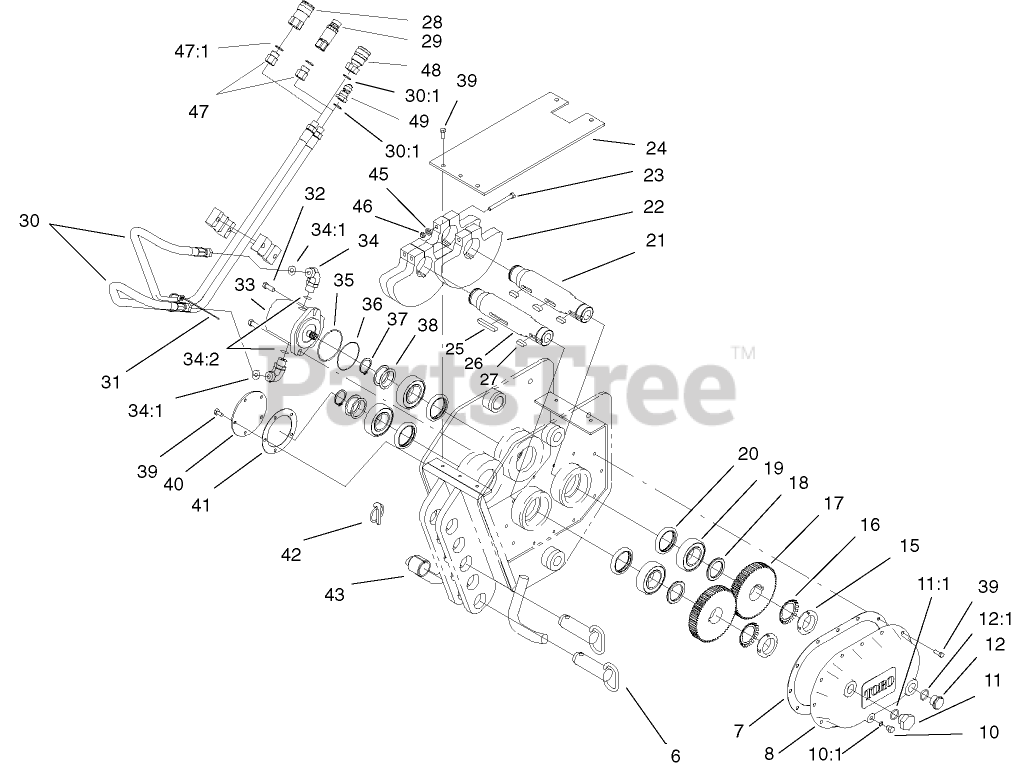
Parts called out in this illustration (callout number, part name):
6	BLADE PIN ASM
7	GASKET
10:1	O-RING
11	PLUG-HH
11:1	O-RING
12	GLASS-SIGHT
12:1	O-RING
16	RETAINER-NUT
18	SPACER
19	BEARING-ROLLER, SPHERICAL
20	SEAL-OIL
21	SHAFT-SPLINED
22	Weight-Counter
23	SCREW-HH
24	PLATE-TOP
25	KEY-LONG
26	SHAFT
27	KEY-SHORT
28	COUPLER-FACE, FLUSH
29	NIPPLE-CONNECT, PRESSURE
30	HOSE-HYDRAULIC
30:1	O-RING
31	TIE-CABLE
32	SCREW-HH
33	MOTOR-HYD
34	FITTING-ELBOW 90
34:1	O-RING
34:2	O-RING
35	RING-PILOT
36	O-RING
37	RING-RETAINING
38	WASHER-THRUST
39	SCREW-FLANGE
40	PLATE-COVER
41	GASKET
42	PIN-LYNCH
43	BUSHING-TENSION
45	Washer-Flat
46	NUT-LOCK, NI
47	ADAPTER-HYD
47:1	O-RING
48	DISCONNECT-QUICK, FEMALE
49	DISCONNECT-QUICK, MALE
